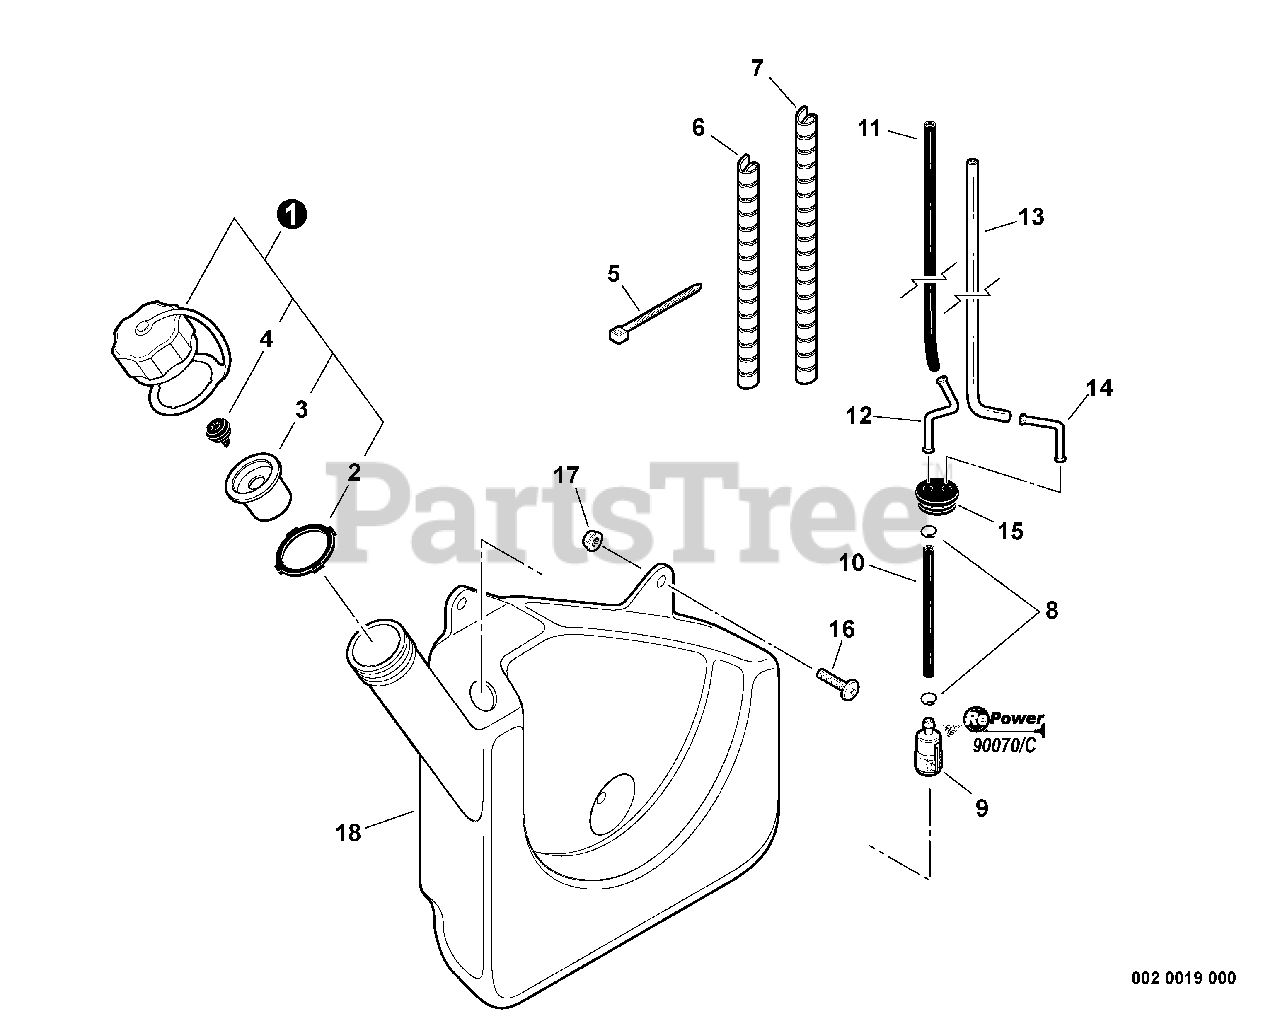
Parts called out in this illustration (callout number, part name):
1	CAP ASSY, FUEL
2	GASKET, FUEL CAP
3	HOLDER, VENT
4	VENT ASSY
5	STRAP, TIE
7	WRAP, SPIRAL
8	CLIP Ø6.5 MM
9	FILTER, FUEL
10	PIPE, FUEL
11	PIPE, FUEL 3×6×280 MM
12	CONNECTOR, PIPE
13	PIPE, FUEL
14	CONNECTOR, PIPE
15	GROMMET
16	SCREW 5×20
17	NUT, FLANGE M5
18	TANK, FUEL
19	TUNE-UP KIT - REPOWER
